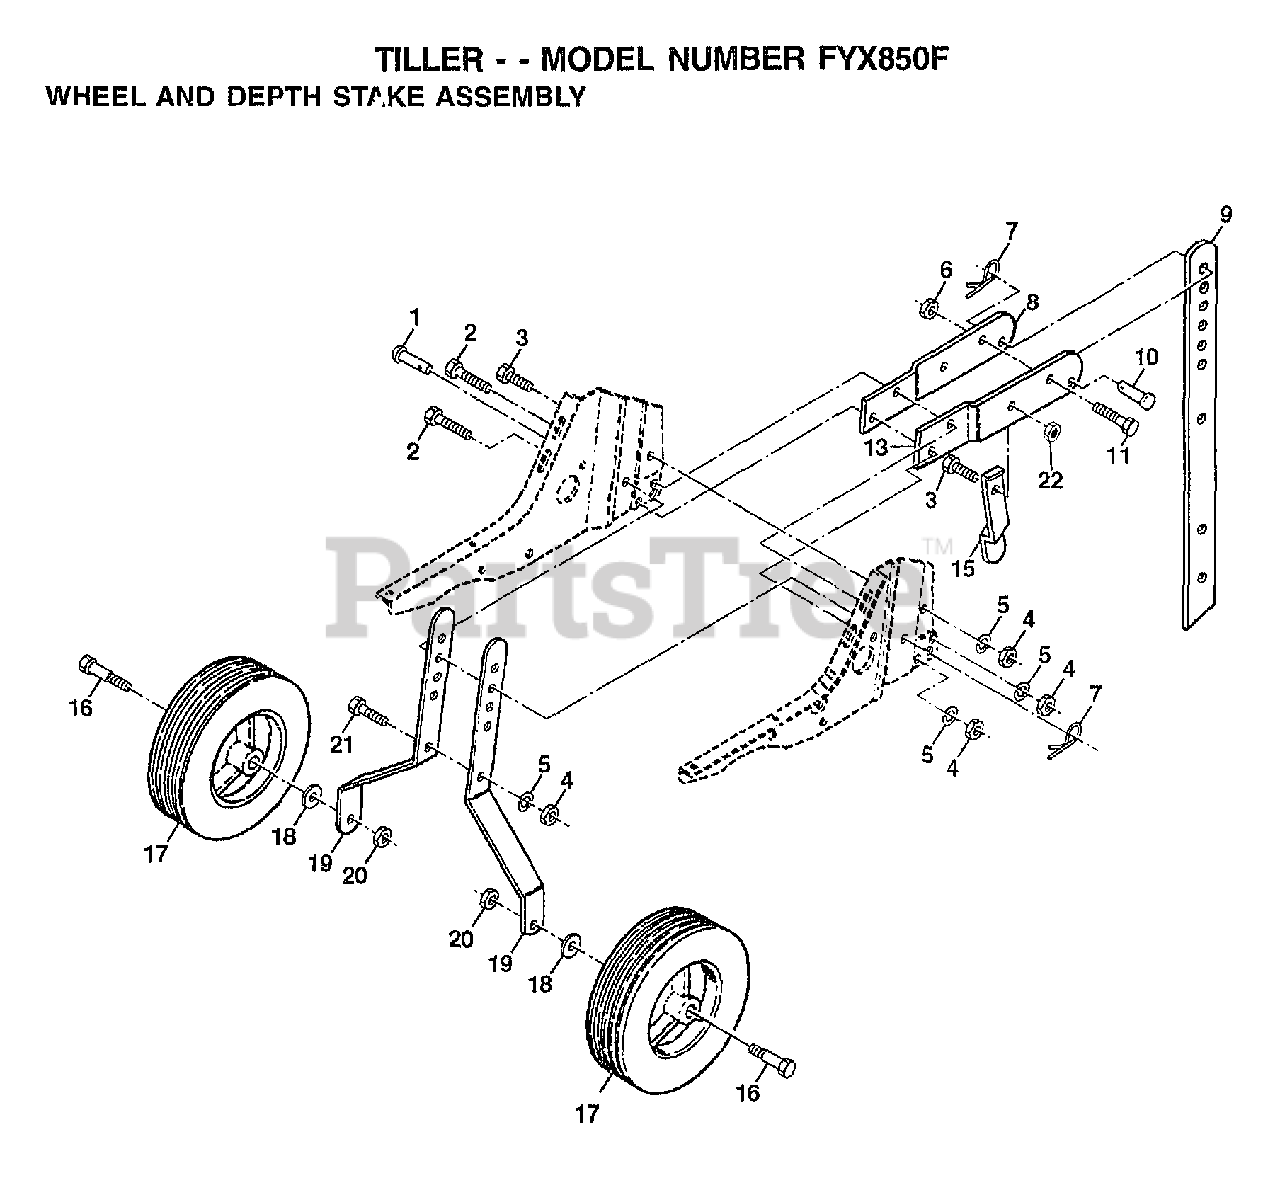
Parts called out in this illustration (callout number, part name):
1	DRILLED RIVET RT
3	BOLT
4	NUT.HEX.5/16-18
5	LOCKWASHER
6	NUT
7	SPRING.RETAINER
11	BOLT
15	STAKE SPRING TI
16	BOLT SHOULDER
18	WASHER
22	NUT
